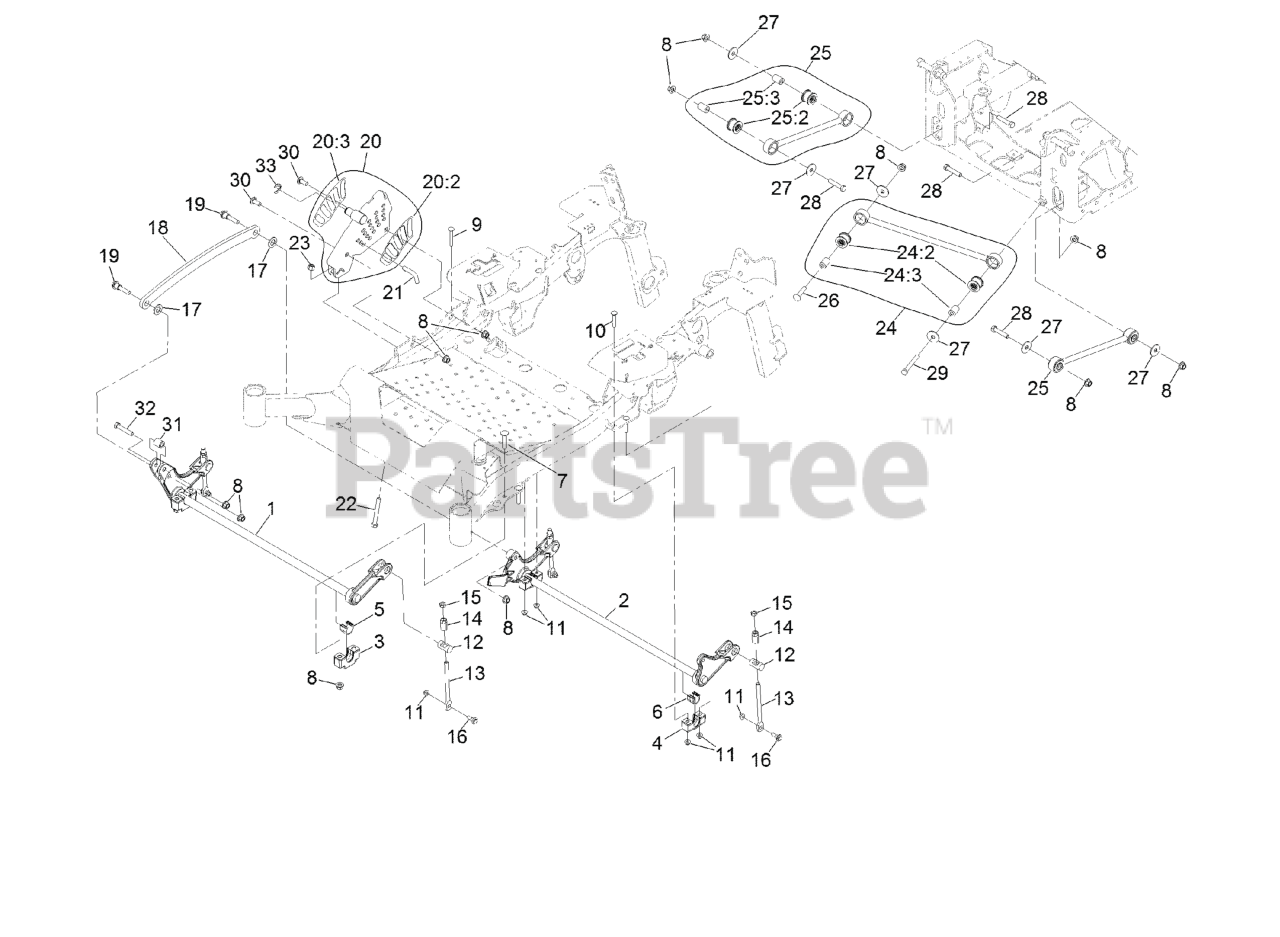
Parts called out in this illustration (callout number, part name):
1	DECKLIFT-FRONT
2	LIFT-DECK, REAR
3	SUPPORT-CROSS SHAFT, BEARING
4	SUPPORT-CROSS SHAFT, BEARING REAR
5	BEARING-CROSS SHAFT, FRON
6	BEARING-CROSS SHAFT, REAR
7	Bolt-Carriage 1/2-13 X 2 1/2 Spl Neck
8	Nut-Lock 1/2-13
9	SCREW-CARR
10	Bolt-Carriage 3/8-16 X 2 1/4
11	NUT-HF, NI
12	TRUNNION
13	LINK-ADJUSTER, DECK LIFT
14	ADJUSTER-LIFT, DECK
15	NUT-JAM
16	SCREW-SHOULDER, HHF
17	WASHER-FLAT
18	LINK-LIFT, DECK
19	SCREW-HHF, SHOULDER
20	HOC ASM
20:2	DECAL-HEIGHT OF CUT
20:3	DECAL-HEIGHT OF CUT, OUTER
21	PIN-HOC
22	BOLT-TAP
23	NUT-LOCK, NI
24	PANHARD ROD ASM
24:2	BUSHING-SUSPENSION, RUBBER
25	DECK STRUT ASM
25:2	BUSHING-SUSPENSION, RUBBER
26	SCREW-CARR
27	WASHER-THRUST
28	SCREW-HH
29	SCREW-HH
30	SCREW-CARR, SHORT NECK
31	SPACER-PIVOT
32	SCREW-HH
33	RING-RETAINING
